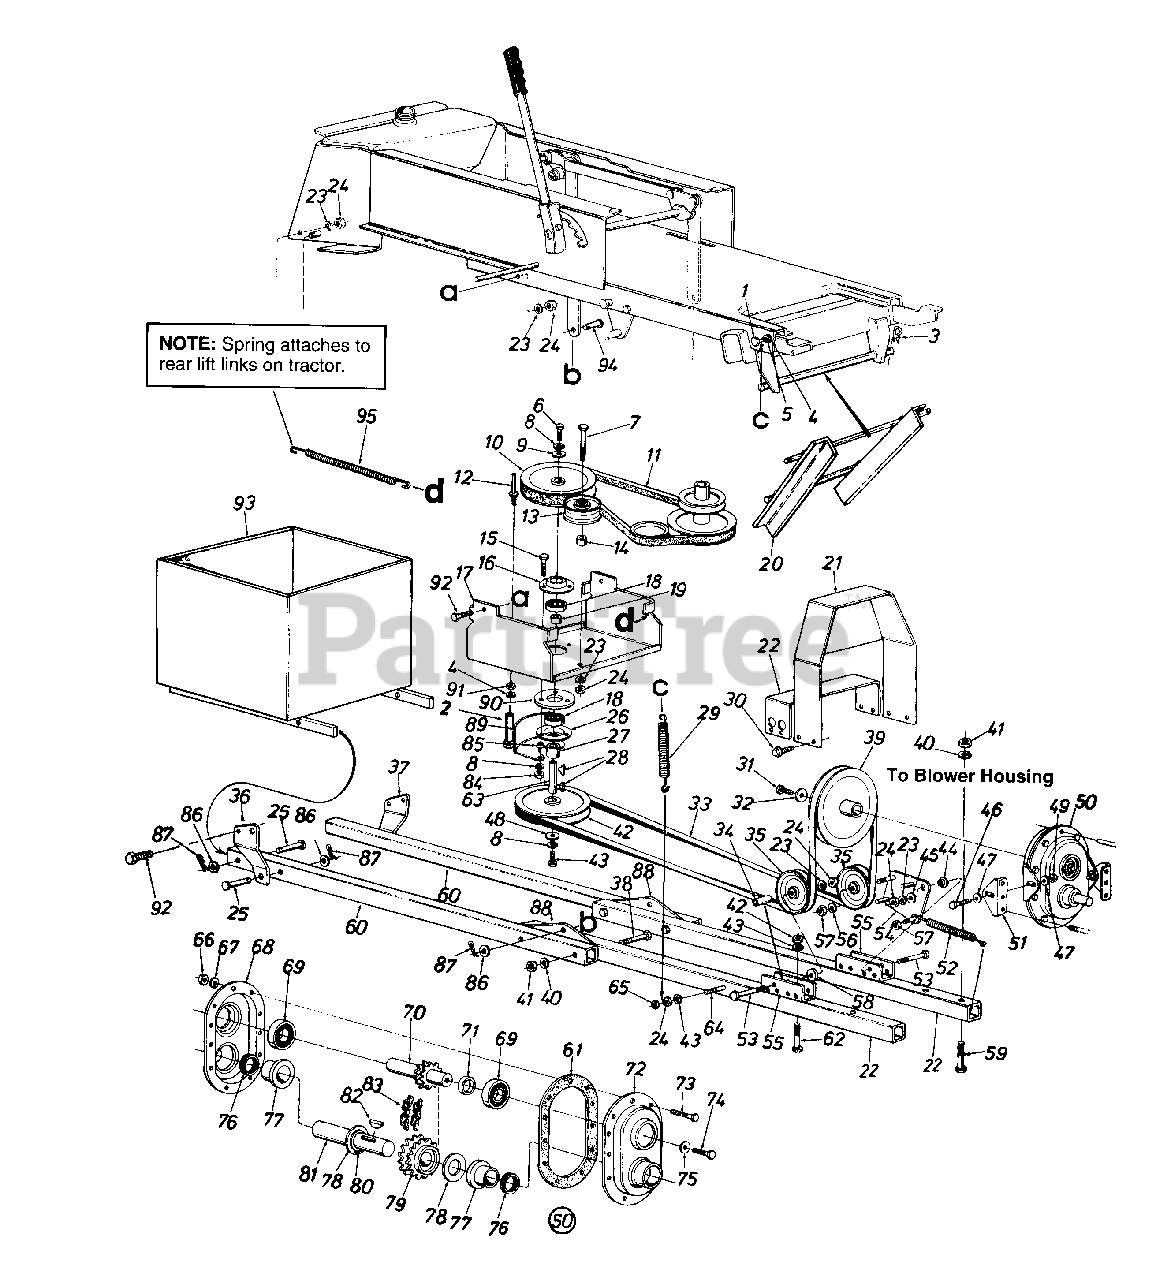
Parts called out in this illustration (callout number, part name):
1	Hex Bolt 5/16-24 x 2" Lg.
2	Clevis Pin Spec. 3/8" Dia. x 2.62" Lg.
3	Intern. Cot. Pin
4	L-Wash. 1/4" I.D.
5	Hex Nut 1/4-28 Thd.
6	Hex L-Scr. 3/8-24 x 1.0" Lg.
7	Hex Bolt 3/8-16 x 2.25" Lg.
8	L-Wash. 3/8" I.D.
9	Fl-Wash.
10	5/8" "V"-Pulley .79" I.D. x .65" O.D.
11	"V"-Belt
12	Belt Guard Pin
13	Fl-Idler 3.75" O.D.
14	Spacer .385" I.D. x .63" O.D. x .76"
15	Hex Bolt 5/16-24 x 1.50
16	Open Brg. Hsg.
19	Spacer .8" I.D. x 1" O.D.
20	Guide Brkt. Ass'y.
21	Belt Cover Ass'y.
24	Hex Nut 3/8-16 Thd.
25	Clevis Pin .50" Dia. x 1.75" Lg.
26	Brg. Hsg. Ass'y.
27	Spacer .8" I.D. x 1" O.D. x .125"
28	Woodruff Key 3/16" x 5/8" HT
29	Helper Spring
30	Hex Wash. HD-Tap Scr. 5/16-18 x .50
31	Hex L-Scr. 3/8-24 x 1.0" Lg.
33	"V"-Belt
34	Spacer .39" I.D. x .62" 0 D. x 1.74" Lg.
35	V-Idler Pulley
39	5/8" "V"-Pulley 7.5" O.D.
40	L-Wash. 1/2" I.D.
41	Hex Nut 1/2-13 Thd.
42	5/8" "V"-Pulley
44	Shld. Spacer
45	Fl-Wash. .4" I.D. x 1.25" O.D. x .16"
46	Hex Bolt 5/16-18 x 1.25" Lg.
47	Bell-Wash. .345" I.D. x .88" O.D. x .06"
49	Hex Nut 5/16-18 Thd.
50	Comp. Chain Gear Box Ass'y.
51	Gear Box Support Brkt.
52	Ext. Spring .6" Lg.
56	L-Wash. 5/16" I.D.
57	Hex Nut 3/8-24 Thd.
59	Hex Bolt 1/2-13 x 3" Lg.
60	Sq. Tubing 43" Lg.
62	Hex Bolt 3/8-16 x 3" Lg.
63	Shaft - .787" Dia. x 3.81" Lg.
65	Hex L-Nut 3/8-16 Thd.
67	Wave Spring Wash. .27" I.D. x .51" 0 D. x .03"
68	Complete Gear Hsg. Half - L.H.
69	Ball Brg. 1" I.D. x 2" O.D.
70	11-2 x .5 Pitch Sprocket Shaft Ass'y.
71	Spacer 1" I.D. x 1.18" O.D. x .44"
72	Comp. Gear Hsg. Half - R.H.
73	Hex Bolt 1/4-28 x 1" Lg.
74	Hex L-Scr. 3/8-24 x 1" Lg.
76	Oil Seal 1.25" I.D.
77	Flange Brg. 1.25" I.D.
78	Fl-Wash. 1.25" I.D. x 2" O.D. x .036"
79	DBL Sprocket 19-2 Teeth x .5" Pitch
80	Snap Ring for 1.25" Dia. Shaft
81	Gear Shaft 1.25 Dia. x 6" Lg.
82	Hi-Pro Key 1/4" x 7/8"
83	40-2 Chain 1/2" Pitch x 25 Links
84	Hex Nut 5/16-24 Thd.
85	Spacer .380" I.D. x .625" O.D. x .227
86	Fl-Wash. .53" I.D. x 1" O.D. x .06"
88	Attaching Plate
91	Hex L-Nut 1/4-20 Thd.
92	Hex Bolt 3/16 x 1" Lg.
93	Weight Box Ass'y.
95	Extension Spring
